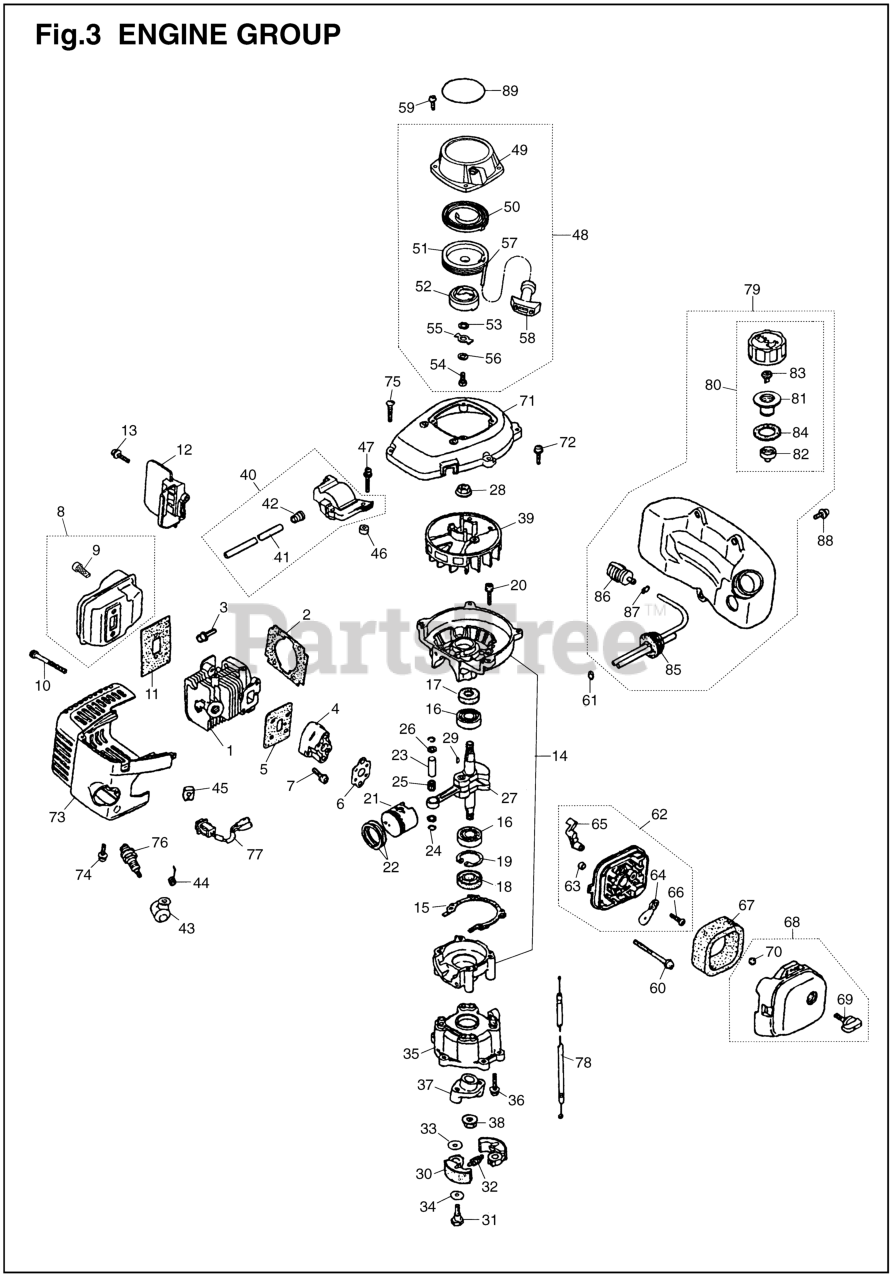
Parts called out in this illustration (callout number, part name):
1	CYLINDER
2	GASKET
9	ARRESTER
10	BOLT, M5 x 50 (RPLS 125230550)
14	CRANKCASE-C
18	SEAL
22	RING
23	PIN.PISTON
25	BEARING
27	CRANKSHAFT (RPLS 560042000)
28	NUT
29	KEY
38	NUT
42	CAP
45	GROMMET
46	SPACER
55	RETAINER
56	WASHER
61	CLIP
64	PLATE.CHOKE
66	SCREW
68	COVER-A
71	COVER.FAN
77	SWITCH-A
83	VALVE
85	PIPE COMPLETE
87	CLIP
